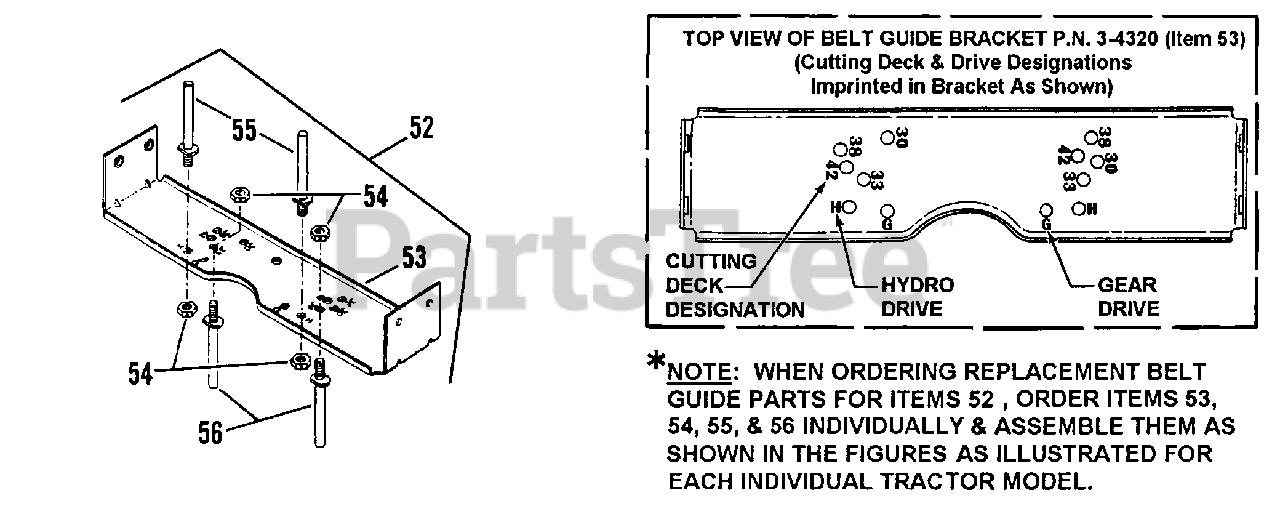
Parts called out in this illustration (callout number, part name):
53	BRACKET, Belt Guide
54	NUT, 5/16-18 Hex Lock
55	STUD, Belt Guide
56	STUD, Belt Guide (33" Models)
